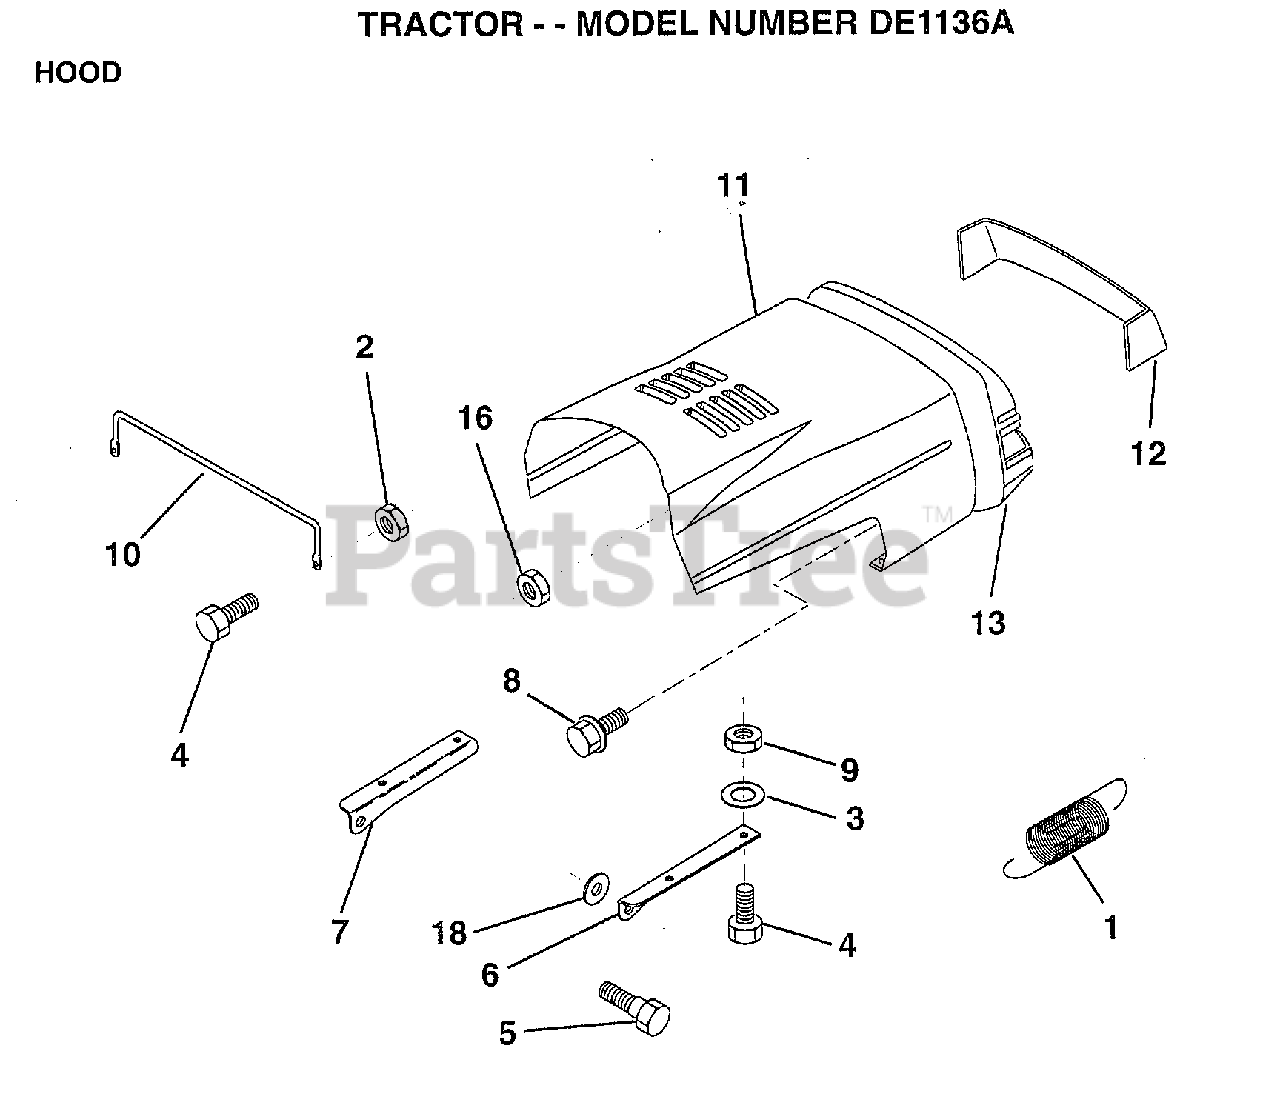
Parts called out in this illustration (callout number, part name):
1	EXT SPRING
2	NUT
3	WASHER
5	BOLT.SHLD.5/16-18
6	BRKT HOOD RH
7	BRKT HOOD LH
8	"SCREW,HWHD.HI-LO#13-16X3/4"
9	NUT
10	"BRACE,HOOD"
12	LENS.HEADLIGHT.BAR
13	GRILL
16	NUT
18	WASHER
